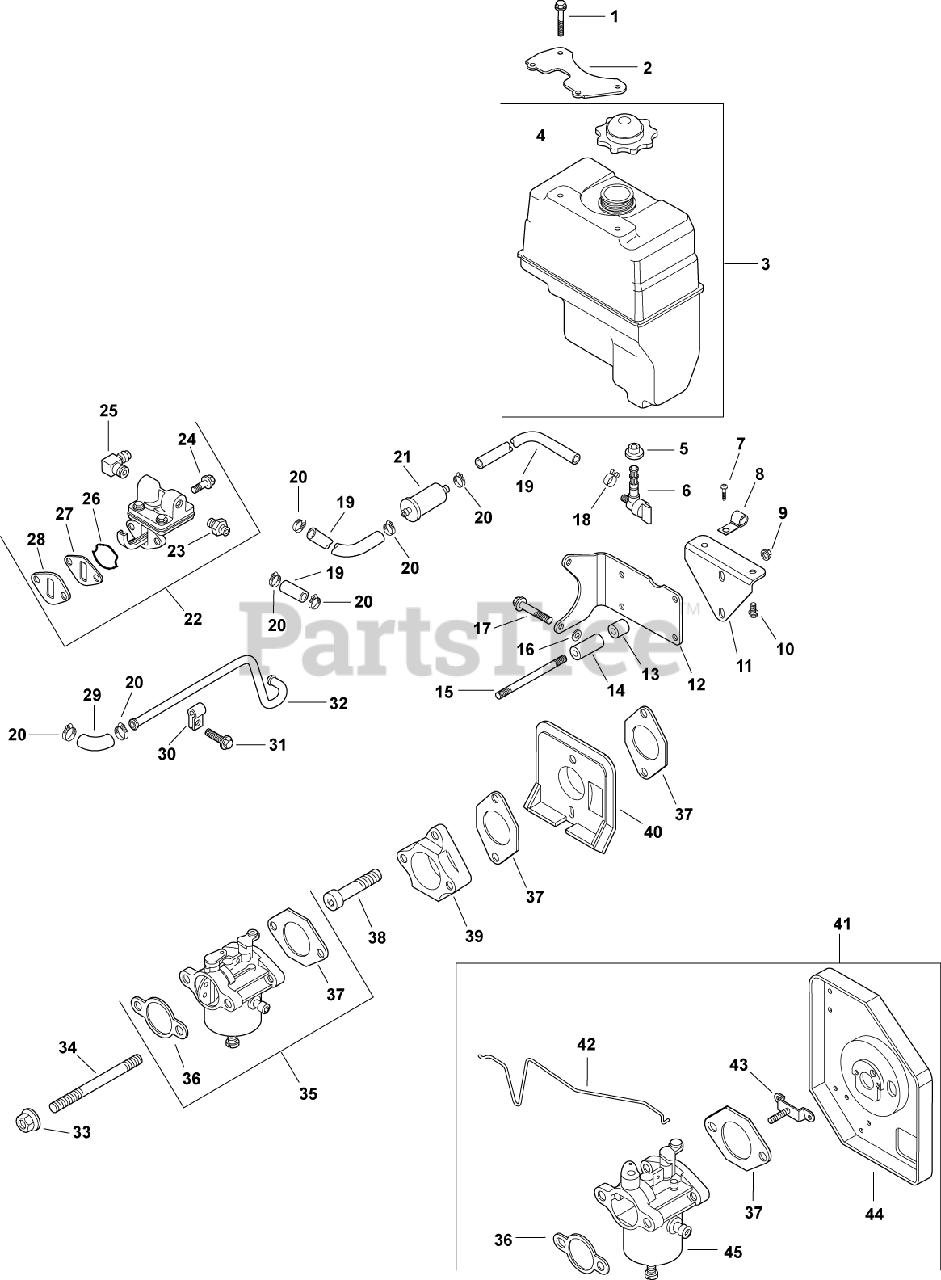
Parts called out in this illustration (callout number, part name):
1	SCREW,FLG THD FRM M6X1.0X25-(#25086395S)
2	BRACKET, FUEL TANK
3	KIT, FUEL TANK
4	CAP, FUEL TANK
5	BUSHING, FUEL TANK
6	VALVE, FUEL SHUT-OFF
7	SCREW, LBD SKT M6x1.0x20-(#25086403S)
8	CLIP, CABLE
9	NUT, FLG M8X1.25
10	SCREW, FLG M6X1.0X12
12	BRACKET, FUEL TANK
14	SPACER, FUEL TANK
15	STUD, M8X1.25X133-USE 25 755 54-S
16	WASHER, FLAT 11/32"
17	SCREW, FLG M8X1.25X50
18	CLAMP, BAND SPRING HOSE-(#2523737S)
19	HOSE,LW PERM.FUEL 24.00"-USE 25 111 81-S
20	CLAMP, HOSE (KM)-USE 25 237 31-S
21	FILTER,FUEL 51 MICRON (FUEL PUMP)
22	KIT, FUEL PUMP
23	KIT, STRAIGHT FITTING
24	SCREW,FLG THD FRM M6X1.0X20-(#25086396S)
25	CONNECTOR, 90 DEG. HOSE
26	O-RING, FUEL PUMP
27	SPACER, FUEL PUMP
28	GASKET, FUEL PUMP
29	HOSE, FUEL LOW-PERMEATION
30	CLIP, TUBE & WIRING (KM)
31	SCREW, FLG THD FRM M5X.8X10
32	LINE, FUEL - DISCONTINUED
33	NUT, FLG M6X1.0
34	STUD,M6X1.0X116
35	KIT, CARBURETOR w/GASKETS
36	GASKET, AIR CLEANER BASE
37	GASKET, CARBURETOR
38	SCREW, SKT CAP M6X1.0X35
39	ADAPTER, CARBURETOR
40	DEFLECTOR, HEAT
41	KIT, CARB. RETROFIT
42	LINKAGE, CHOKE
43	BRACKET, AIR CLEANER
44	BASE, AIR CLEANER
45	CARBURETOR W/GASEKTS - USE 12 853 139-S
